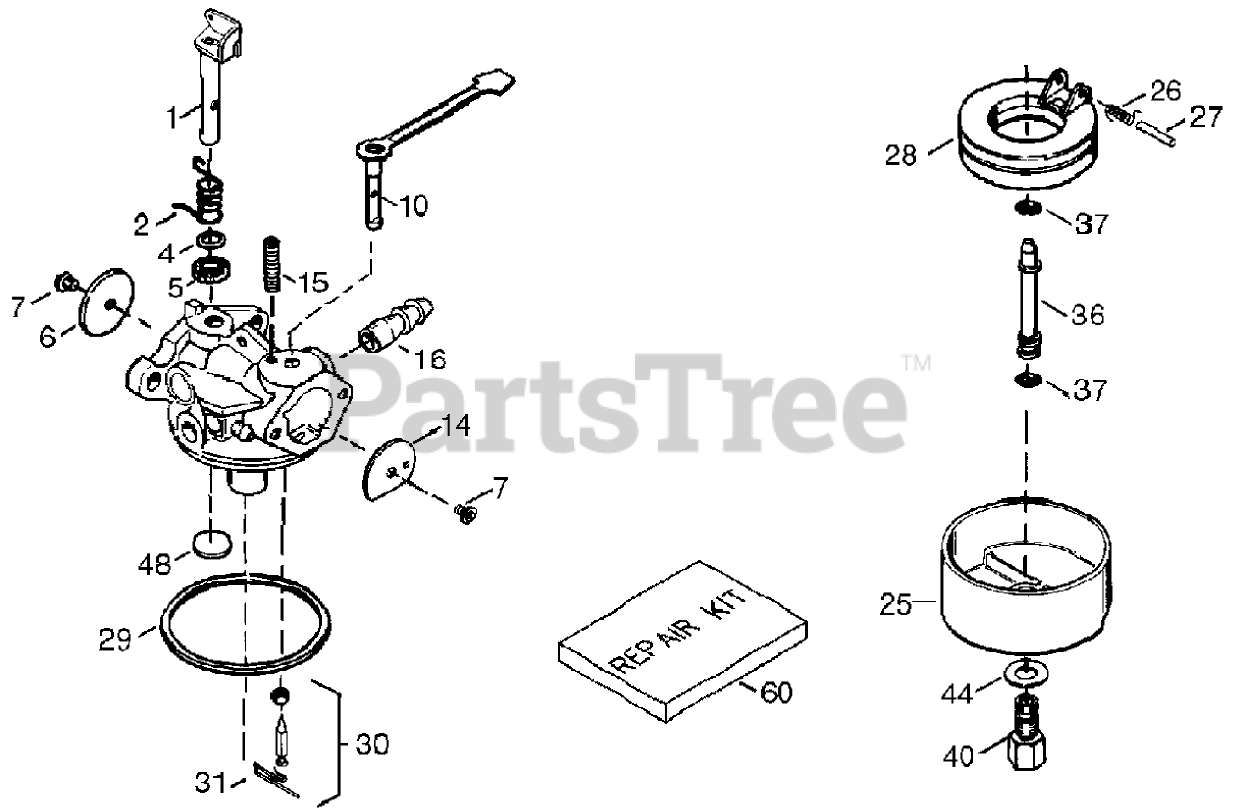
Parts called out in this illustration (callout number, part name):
1	Throttle Shaft and Lever ASM
2	Spring-Trottle, Return
4	Washer-Seal, Dust
5	Seal-Dust
6	Throttle-Shutter
7	Screw-Shutter
10	Choke Shaft and Lever ASM
14	Shutter-Choke
15	Spring-Positioning, Choke
16	Fitting-Fuel
25	Bowl-Float (no drain)
26	Spring-Float, Dampening
27	Shaft-Float
28	Float
29	O Ring-Bowl, Float
30	Inlet Needle, Seat & Clip (Incl. 31)
31	Clip-Spring
36	Tube-Nozzle, Main
40	Nut-Bowl, High Speed
44	Washer-Nut, Bowl
48	Plug-Welch, Atmospheric Vent
60	Repair Kit
